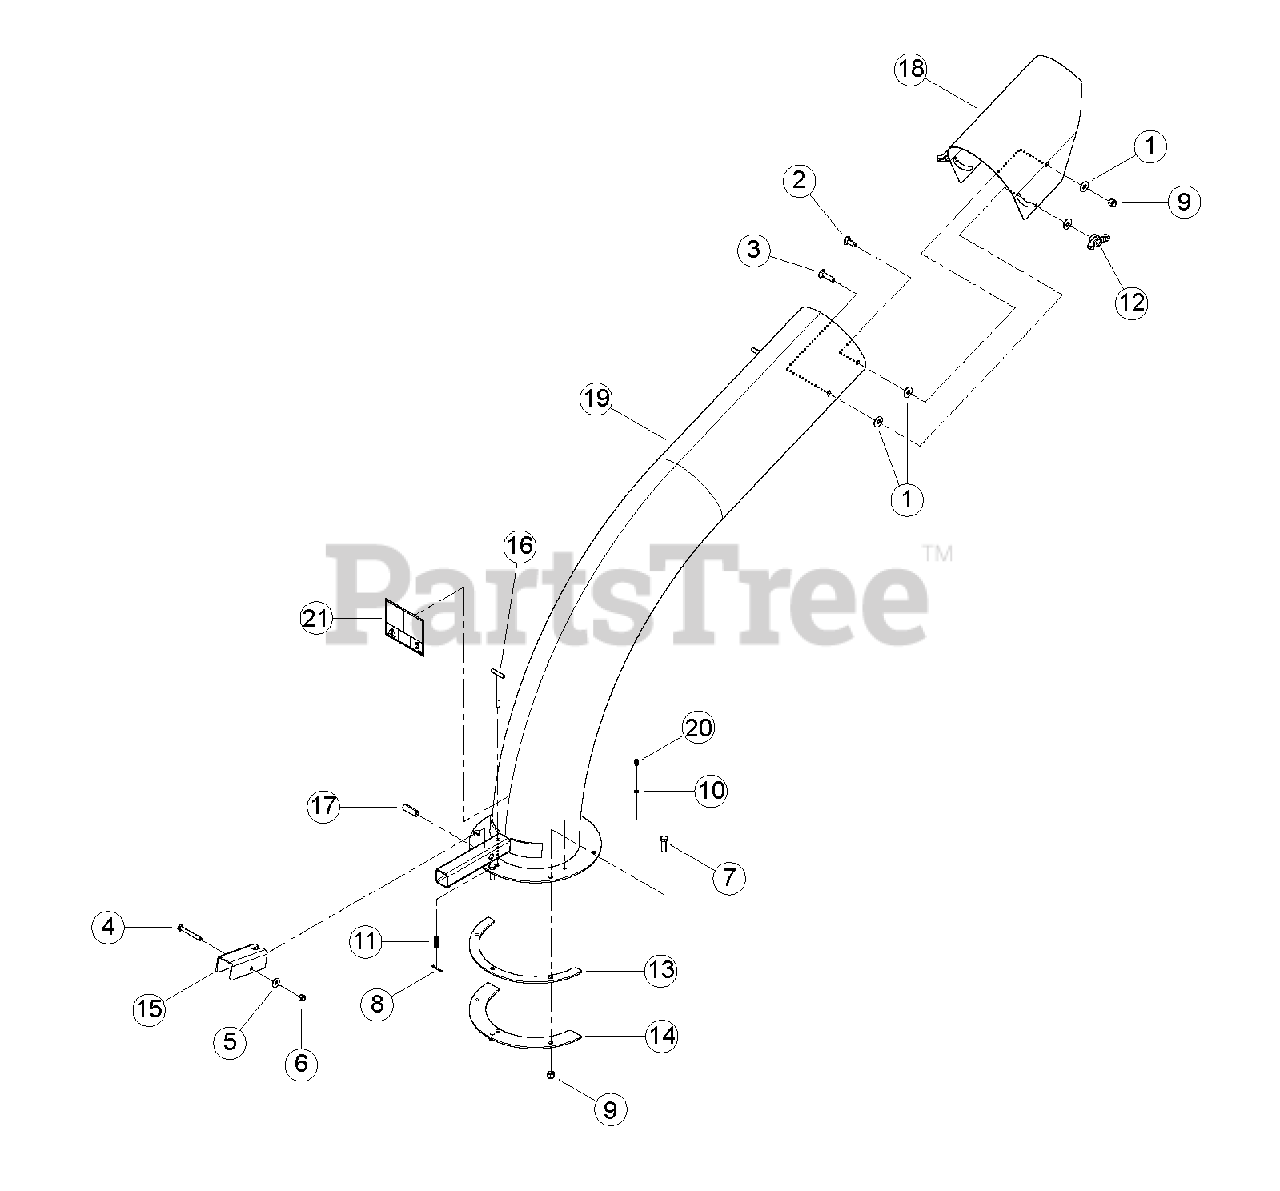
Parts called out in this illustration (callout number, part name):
1	WASHER, 3/8 FLAT ZP
2	BOLT, 3/8 X 1 CRG GR5 NC ZP
3	BOLT, 3/8 X 1-1/2 CRG GR5 NC ZP
4	BOLT, 5/16 X 2-1/2 HX CAP GR5 ZP
5	WASHER, 5/16 FLAT ZP
6	NUT, 5/16 NE NYLOCK ZP
7	BOLT, 3/8 X 1-1/4 HEX HD GR5 ZP
8	PIN, 1/8 X 1 ZP COTTER
9	NUT, 3/8 NE NYLOCK ZP
10	WASHER, .254 X .400 X .048 FLAT
11	SPRING, LOCK COMPRESSION
12	KNOB, 3/8-16 UNC FEMALE TEE
13	RING, DISCHARGE SPACER
14	RING, DISCHARGE CLAMP
15	LEVER, DISCHARGE LOCK
16	WELDMENT, DISCHARGE LOCK PIN
17	TUBE, DISCHARGE LOCK PIVOT
18	CAP, 8 IN. DISCHARGE CHUTE
19	ASSEMBLY, 8 INCH DISCHARGE SERVICE PART
20	FITTING, 1/4 SELF-TAP GREASE
21	DECAL, DISCHARGE DEBRIS & LOCK
